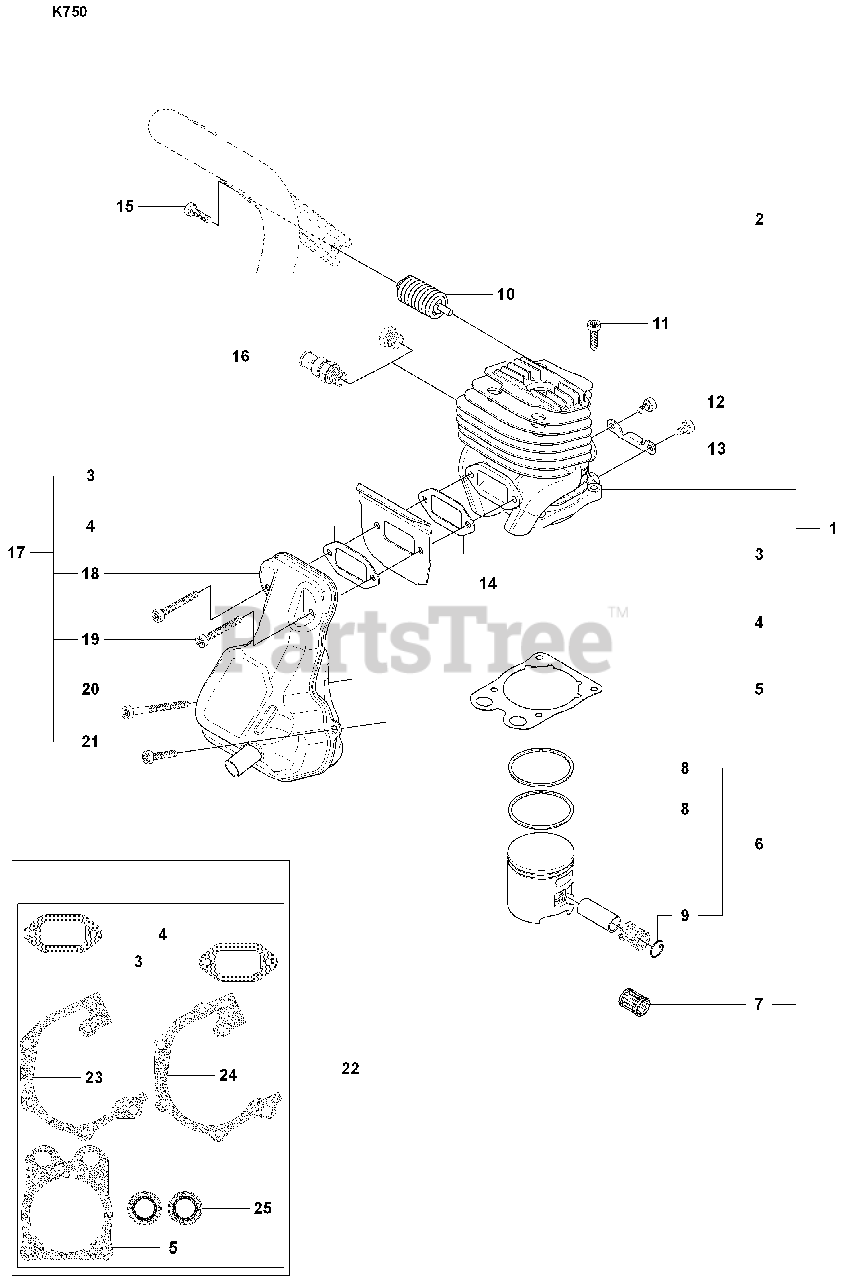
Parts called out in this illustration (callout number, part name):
1	CYLINDER ASSY
4	GASKET MUFFLER
5	GASKET CYLINDER BASE
6	PISTON ASSY
7	NEEDLE BEARING
8	PISTON RING
10	VIB.INSULATOR
14	COOLING PLATE
16	DECOMPRESSION VALVE
17	MUFFLER KIT
18	MUFFLER
22	GASKET KIT
23	GASKET CRANKCASE
24	GASKET CRANKCASE
25	SEALING RING
